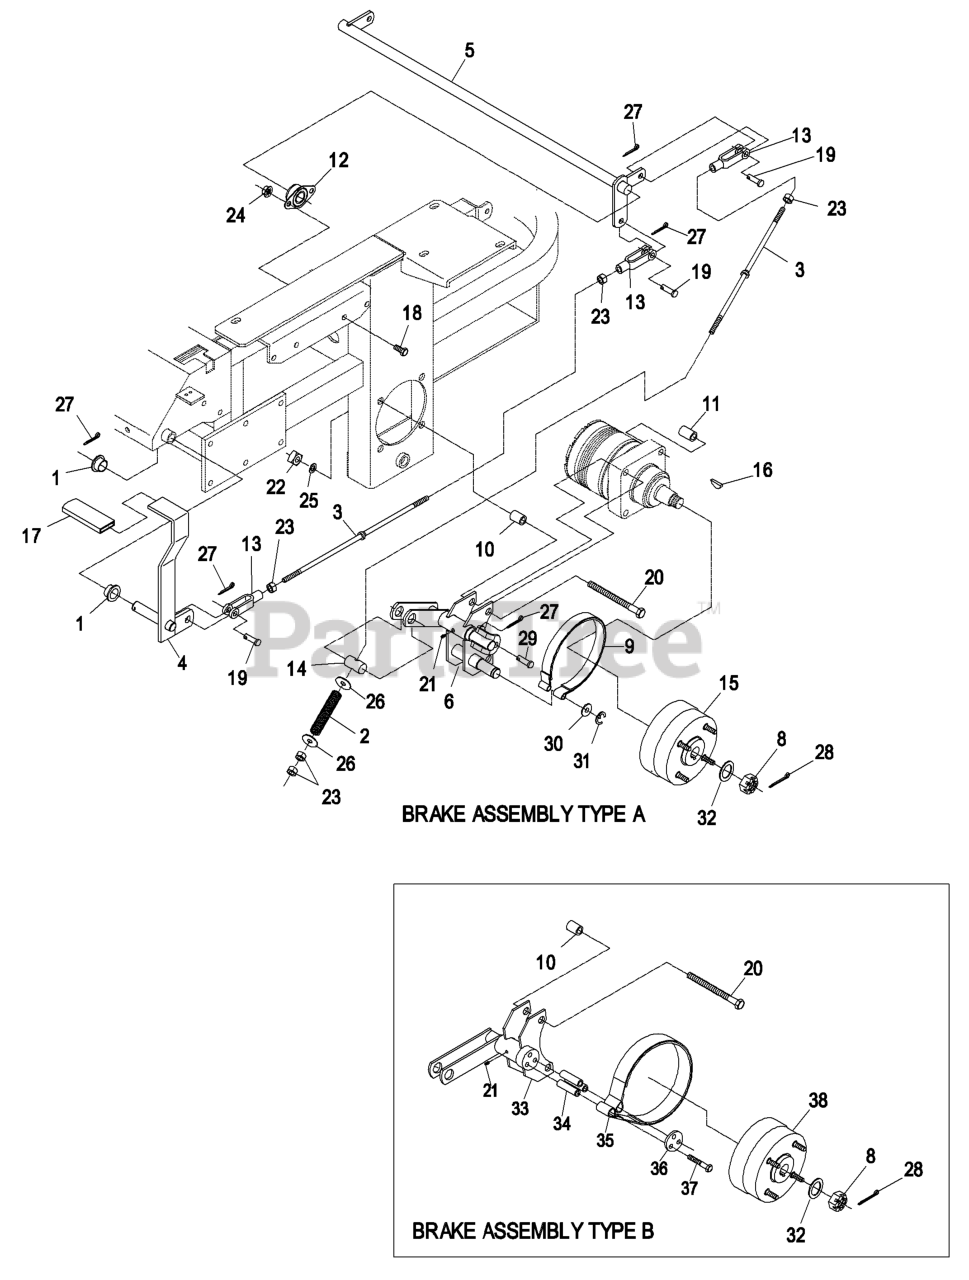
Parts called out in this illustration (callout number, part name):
1	BEARING-CONTROL
2	SPRING-BRAKE
3	ROD-BRAKE
4	BRAKE LEVER ASM
5	SHAFT-BRAKE
6	WLD,BRACKET LH 52
9	BAND,BRAKE
10	SPACER-WHEEL, SHORT
11	SPACER-WHEEL, LONG
12	BEARING-FLANGE, SIDE
13	YOKE-LINKAGE, BRAKE
14	PIN-TRUNION
17	GRIP-LEVER
18	SCREW-HH
19	PIN-CLEVIS
20	SCREW-HH
21	FITTING-GREASE
23	NUT-HEX
24	NUT-HHF, WHIZ
25	WASHER-LOCK
26	WASHER-FLAT
27	PIN-COTTER
28	PIN-COTTER
29	PIN,CLEVIS 3/8X2
30	WASHER-FLAT
31	E-RING
32	WASHER-SPACER
33	BRACKET-BRAKE
34	SPACER
36	RETAINER-BAND, BRAKE
37	SCREW-HH
38	WHEEL HUB ASM
